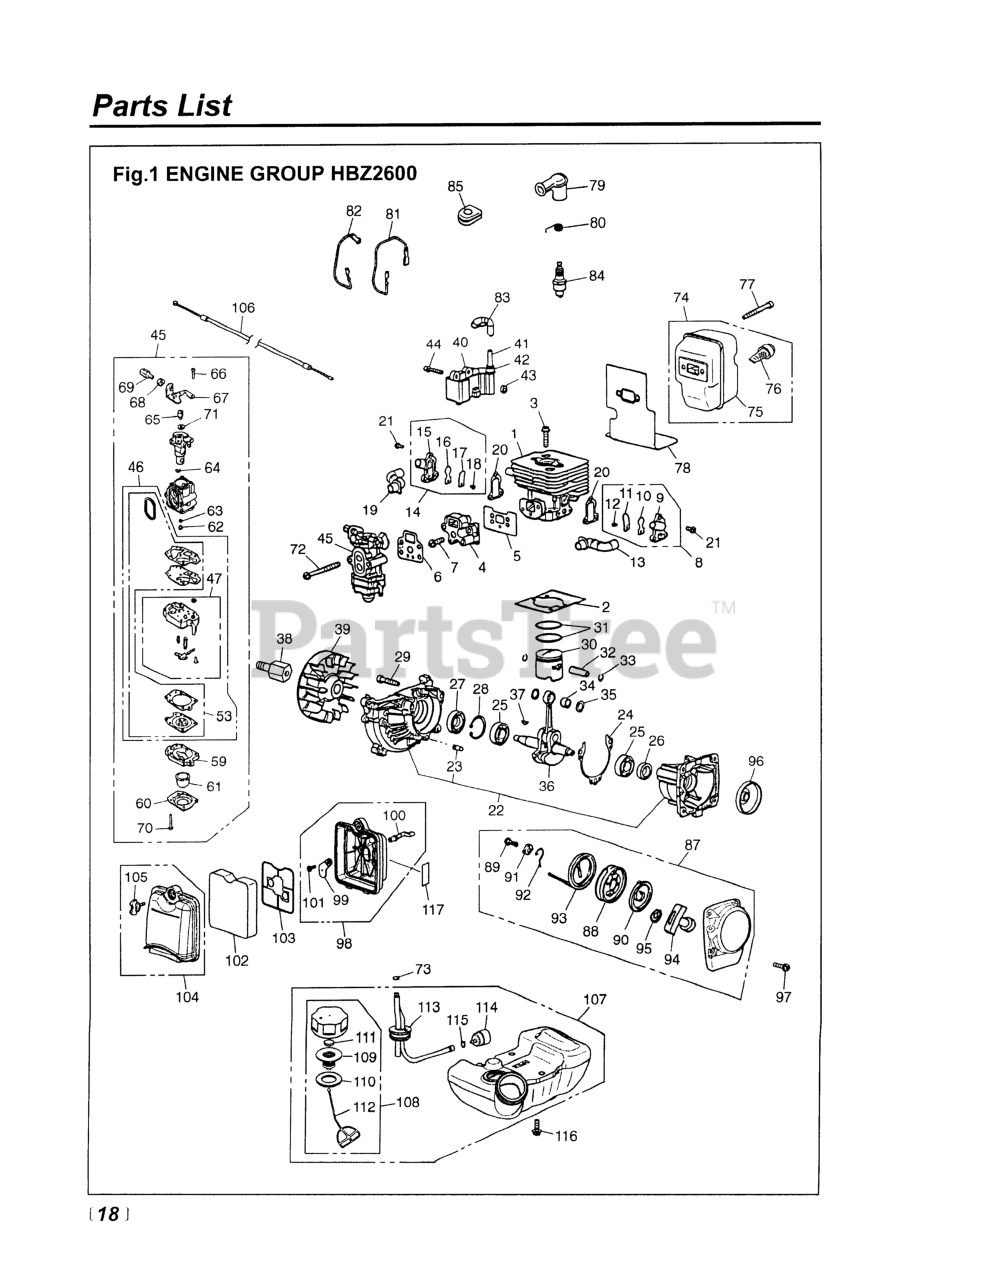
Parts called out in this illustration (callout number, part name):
1	CYLINDER (RPLS -12110)
2	GASKET, BASE
3	BOLT
4	INSULATOR (RPLS. -13160/13161)
5	GASKET INSULATOR
6	GASKET, CARBURETOR
7	BOLT (RPLS 2850-14220)
9	CASE VALVE
10	VALVE, REED
11	STOPPER
12	SCREW, M3 x 8
13	PIPE, AIR
16	VALVE, REED
17	STOPPER
18	SCREW, M3 x 8
19	PIPE, AIR (F)
20	GASKET, VALVE
21	BOLT, TORX
22	CRANKCASE-C
23	PIN
24	GASKET
25	BEARING
26	SEAL
27	SEAL, OIL (RPLS 1140-21220)
28	RING, SNAP, M28 x 1.2
29	BOLT
30	PISTON
31	RING, PISTON
32	PIN
33	RING, SNAP (RPLS 1101-41320)
34	BEARING (RPLS 1140-41330)
35	WASHER
36	CRANKSHAFT COMPLETE
37	KEY
38	EXTENSION
39	ROTOR
40	COIL-A
41	CORD (BLACK)
42	CAP
43	SPACER (RPLS -71260)
44	BOLT TORX
45	CARBURATOR (USE 848-F3C-8102)
47	PUMP BODY ASSEMBLY
53	KIT, GASKET (REPLACES-06020)
59	BODY, PURGE
60	COVER, PUMP
61	PUMP, PRIMING
62	JET (REPLACES 4810-81250)
63	RING, O
64	RING
65	SWIVEL
66	SCREW
68	NUT, CABLE ADJUSTER
69	SCREW, CABLE ADJUSTER
70	SCREW
71	WASHER
72	BOLT
73	CLIP
74	MUFFLER-ASSY
76	ARRESTER
77	BOLT,TORX, M5X70
78	GASKET
80	SPRING
81	CORD (BLACK)
82	CORD, EARTH (RED)
83	TUBE
85	GROMMET
87	RECOIL ASSEMBLY
88	REEL
89	SCREW
90	SPRING, SPIRAL
91	COLLAR
92	ARM
93	ROPE (REPLACES 4500-75160)
94	KNOB (RPLS -75420)
95	PLATE, STOPPER
96	PULLEY
97	BOLT
98	BODY A
99	PLATE, CHOKE
100	LEVER
101	SCREW
102	ELEMENT
105	KNOB
106	CABLE COMP (RPLS, -83100)
108	CAP ASSY (RPLS -85201)
109	HOLDER (REPLACES -85230)
110	PACKING
111	FILTER
112	STOPPER
113	PIPE COMPLETE
114	FILTER (RPLS 1850-85300)
115	CLIP (REPLACES 2841-31280)
116	BOLT
117	LABEL
